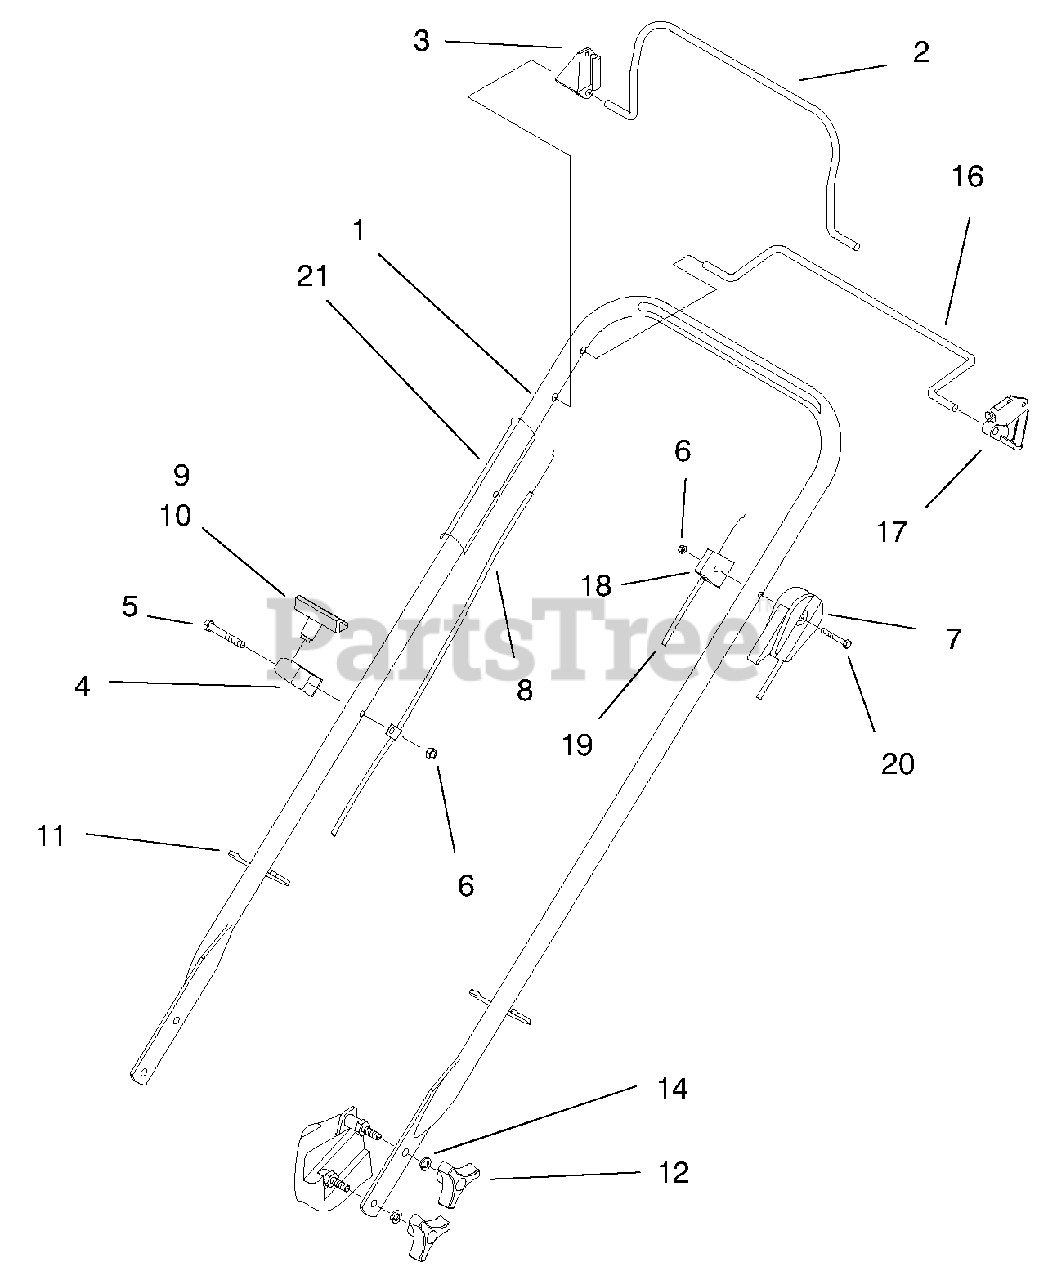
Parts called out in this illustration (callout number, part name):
2	Bail-Brake
3	STOP-PIVOT
4	GUIDE-ROPE
5	SCREW-HH
6	NUT-LOCK, NI
7	CABLE - THROTTLE
8	CABLE - BRAKE
9	CLIP-STARTER
10	HANDLE-START
11	TIE-CABLE
12	HANDLE-KNOB
14	WASHER-LOCK
16	Bail-Control
17	STOP-PIVOT
18	ANCHOR-CABLE, UPPER
19	CABLE - TRACTION
20	SCREW-HH
21	DECAL - OPERATION
